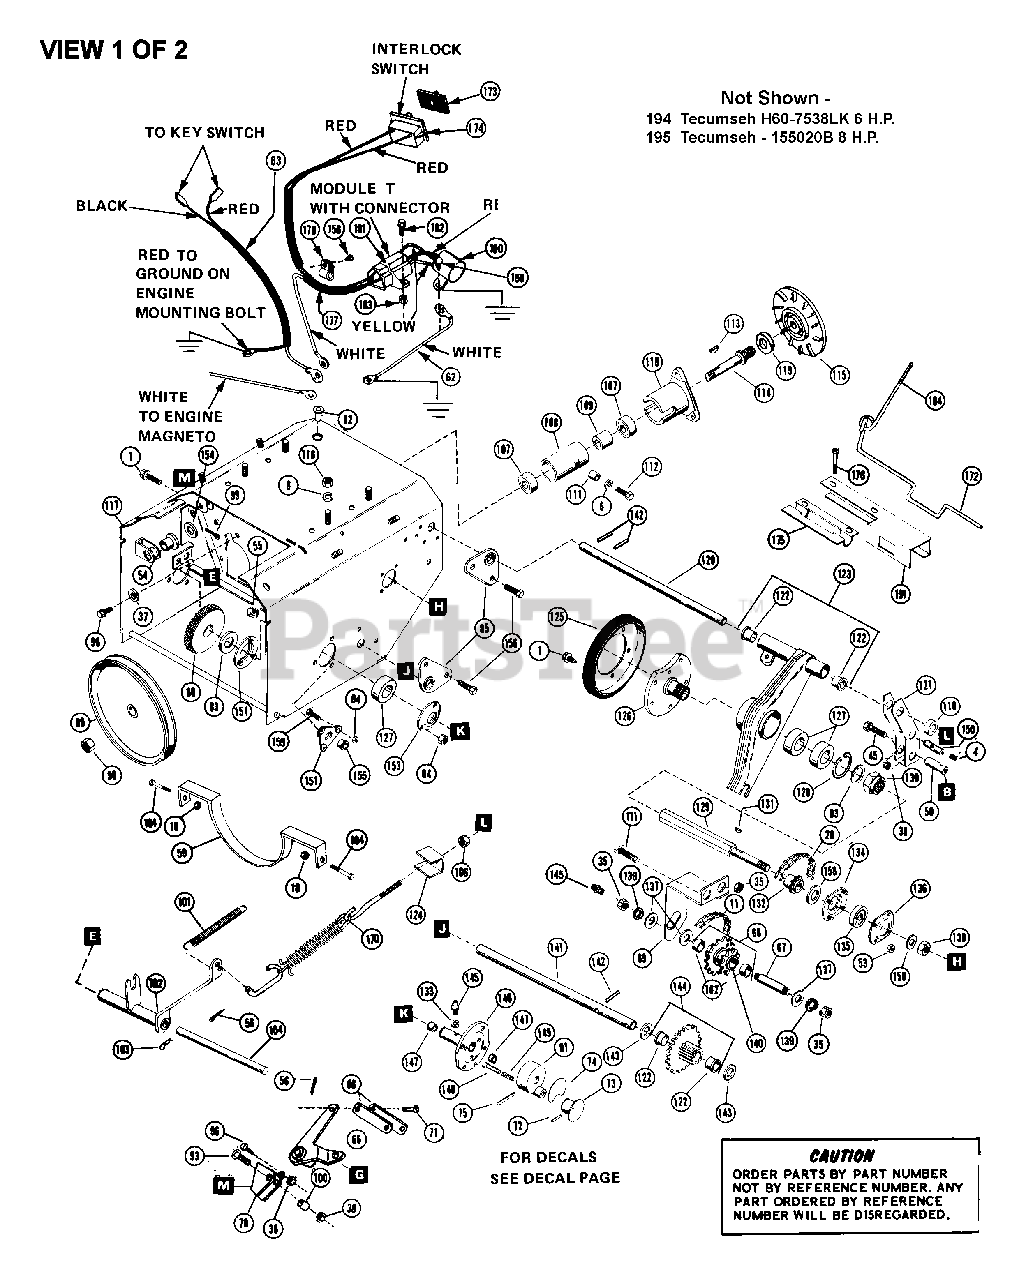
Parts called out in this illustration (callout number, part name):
101	SG-TENS .080X.73X3.06 WLD 20
102	FORK, CLUTCH
103	PIN-HAIR INT .08X.38X1.42 YWZC
104	ROD, FORK PIVOT
105	SPCR, BRG .315X.50X.688X.281
106	NUT-LK-NYL.312-18 PL
107	BRG-BALL .625X1.375X.44
108	SPINDLE HOUSING
109	BEARING SPACER
110	DRIVE SPINDLE HOUSING
112	BLT-HEX .31-18X1.00 PL GR 2
113	KEY-WDRF .125X.500X.203 SAE 3
114	SPINDLE
115	DRIVE PLATE
116	NUT-HEX .312-18
117	FRAME - TRACTOR 6 HP
117	FRAME - TRACTOR
118	SPACER 1.00 X .64 X .38
119	DRIVE DISC SPACER 1.3X.76X.19
120	CARRIER SHAFT
121	CLUTCH ENGAGEMENT YOKE
122	BSHG-FLG .625X.750X.500X.875BR
123	DISC CARRIER SERVICE ASSEMBLY
124	ADAPTER SPACER
125	FRICTION DISC
126	FRICTION DISC HUB
127	BRG-BALL .876 X 1.750 X .50
128	RG-RTNG-INT 1.750X.062
129	HEX SHAFT
130	NUT-LK-NYL .875-14
131	KEY-WDRF .125X.625X.250 SAE5
132	9 TOOTH SPROCKET
133	WSHR-LK .250X.047 LT PL
134	BEARING FLANGE
135	BRG-BALL .500X1.38X.437
136	BEARING FLANGE
137	WSHR-FL-STL .382X.812X.062
138	NUT-LK-CTR .50-20 PL
139	WSHR-LK .375X.130
140	REDUCTION SPROCKET
141	PINION SHAFT
142	PIN-ROLL .156X1.00
143	WSHR-FL-STL .630X1.005X.062 PL
144	PINION AND SPROCKET ASSY.
145	SPIN DRIVE ZERK FITTING
146	L. H. AXLE ASSEM
146	L H AXLE ASSEMBLY
147	BSHG-SLV .562X.625X.625 BRZ
149	SG-COMP .028X.34X1.062 WLD75
150	ADAPTER
151	BEARING FLANGE
151	SUPPORT, BEARING
152	BLT-HEX .31-18X1.25 PL GR2
153	BEARING FLANGE
154	WSHR-FL-STL .380X.626X.033
155	BSHG-FLG.875X1X.625X1.250 BR
156	BLT-SERHFWH .25-20X.50 PL
157	WSHR-FL-STL .880X1.380X.062
158	WSHR-FL-STL .505X1.000X.062
159	SCR-SLTR-SERNK .25-20X.62 PL
160	BLT-HEX .31-18X2.00 PL GR2
162	BSHG-SLV .500X.625X.500 BR
163	BRACKET
164	BLT-HEX .25-20X.50 PL GR2
165	WSHR-LK .250X.077 HVY PL
166	WSHR-FL-STL.344X.688X.065PL
167	SPARK PLUG SHIELD
168	NUT .625-32 ALUM
170	SPRING ASSEMBLY
171	SCR-TAP .375-16X.75 HWH PL TR
172	SWITCH ACTUATOR
173	SWITCH BOOT
175	ROD RETAINER
176	SCR-TAP 10-24X.375 CRPH 1A
177	WIRING HARNESS
180	MODULE T SERVICE ASSEMBLY
181	CONNECTOR
182	BLT-HEX 10-24X.38 PL GR2
183	NUT-KEPS 10-24 PL
184	LOWER ROD INTERLOCK
185	NUT-HEX .250-20 PL
186	UPPER ROD INTERLOCK
187	PIN-COTR .06X.50
188	HANDLE INTERLOCK
189	PIN PIVOT
190	PUSH NUT, .25
191	SWITCH RETAINER
192	SPACER .50 X .32 X .42
193	KEYS
194	Tecumseh H60-7538LK 6 H.P.
195	Tecumseh - 155020B 8 H.P.
